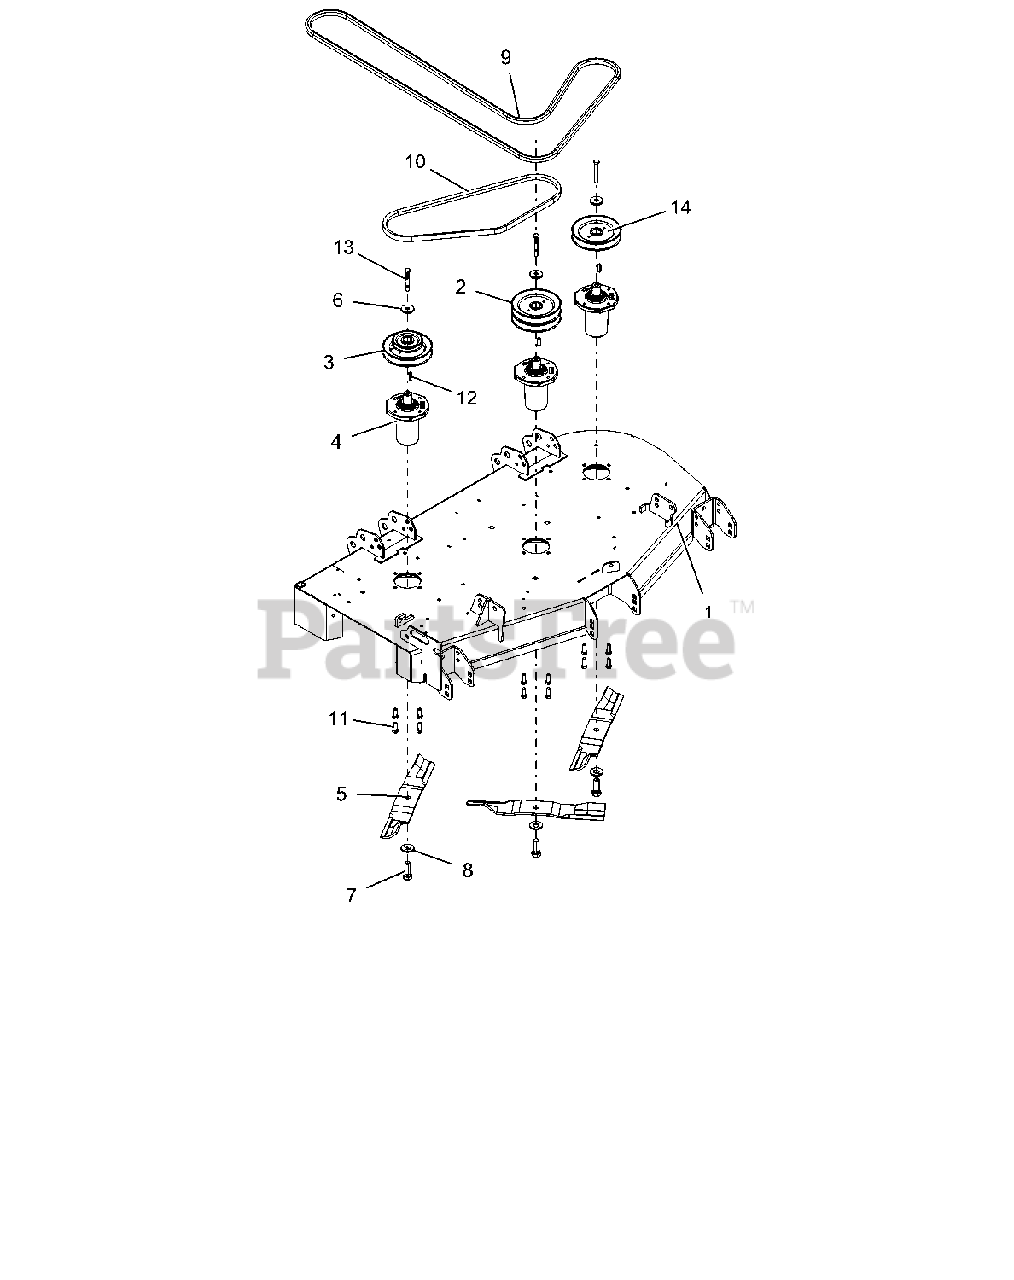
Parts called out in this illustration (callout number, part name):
1	KIT,DECK - 48" W/SAFETY DECALS
2	PULLEY, DOUBLE-1"ID X 5.75"OD
3	PULLEY, DBL-1"IDX5.75"&3.50"OD
4	ASM, MAINT FREE SPINDLE
5	BLADE, 16.19" MOWER (HI-LIFT)
6	RETAINER, SHEAVE
7	BLT-HEX .62-18X1.75 GR8 YWZC
8	WSHR-BLVL .669X1.535X.138
9	HEX BELT, BB-WRAPPED
10	V-BELT, B-COGGED
11	BLT-HEX .38-16X1.0 GR8 YZ EP30
12	KEY, SQ .25X.25X1.00 RC 40-50
13	BLT-HEX .38-16X2.75 GR8 YWZC
14	PULLEY, V-1" ID X 5.75" OD
